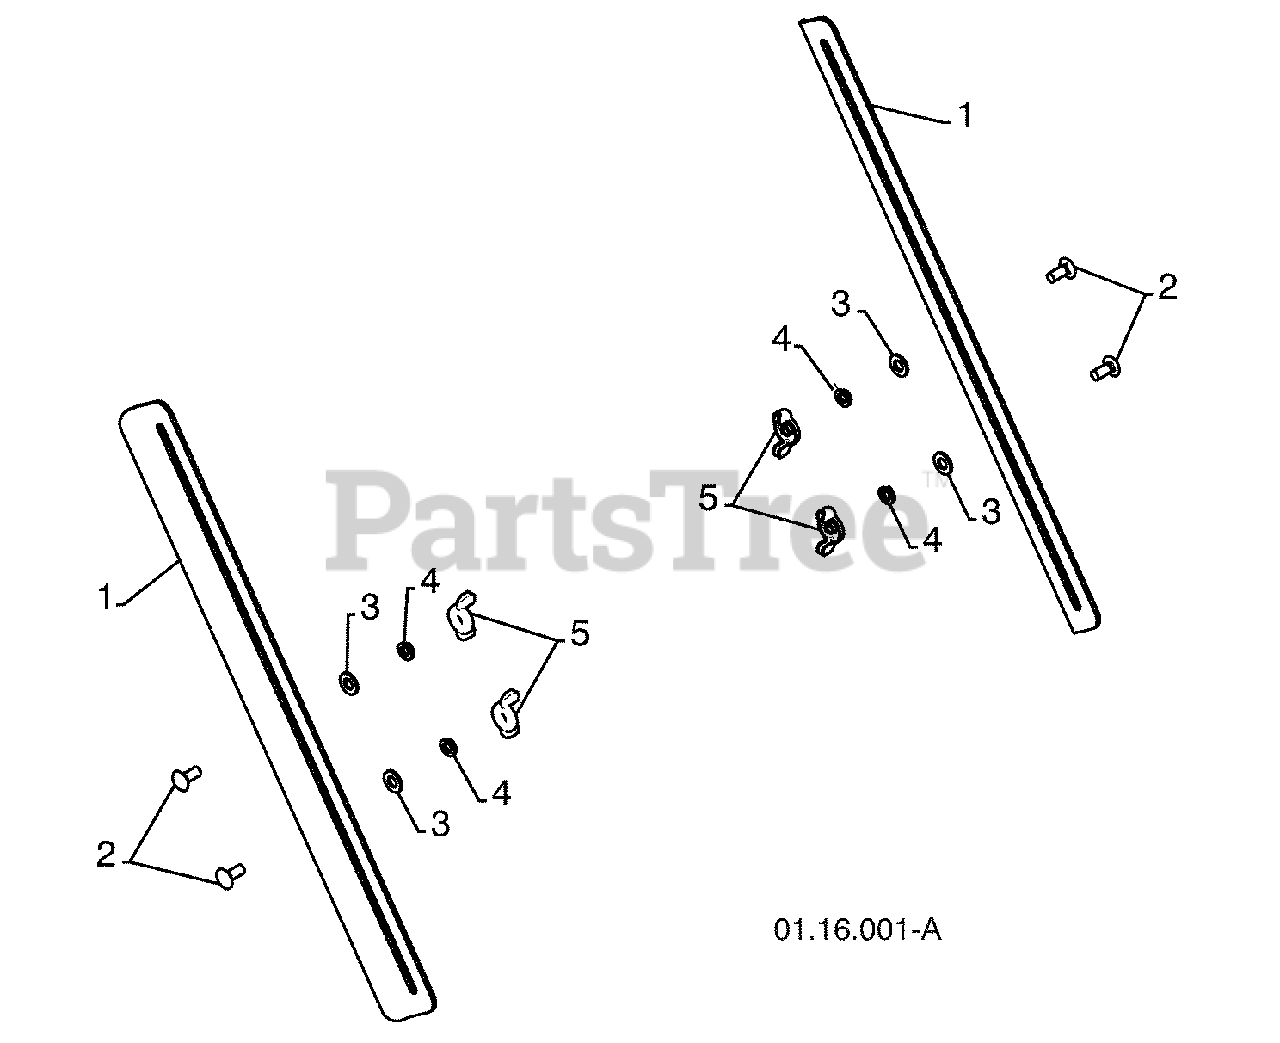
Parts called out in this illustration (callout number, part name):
1	DRIFT CUTTER BAR
2	CARRIAGE BOLT 5/16-18 X .750
3	PLASTIC WASHER
4	LOCKWASHER 5/16
5	NUT 5/16-18
